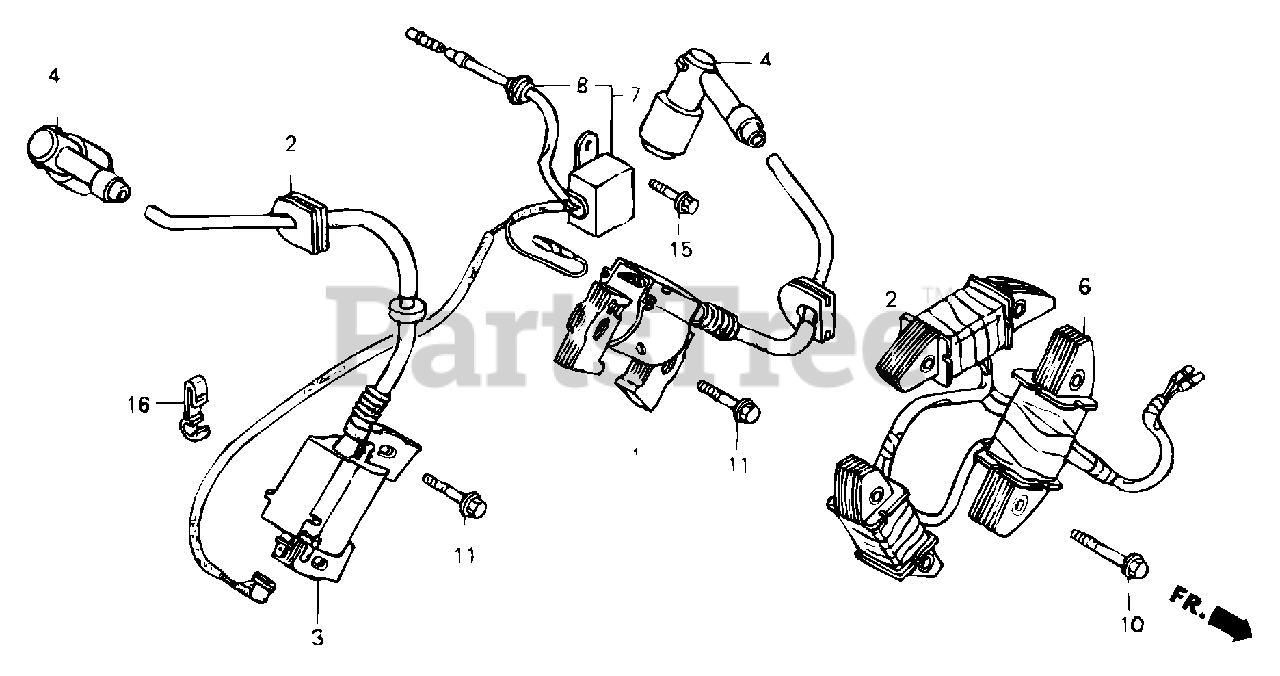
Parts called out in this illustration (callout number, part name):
1	Coil Assembly., R. Ignition
2	Grommet, Ignition Wire
3	Coil Assembly., L. Ignition
4	Cap Assembly., Noise Suppressor
6	Coil Assembly., Charge (12V/20A)
7	Diode Assembly., Engine Stop
8	Grommet, Tool
10	Bolt, Flange (6x32)
11	Bolt, Flange (6x32)
15	Bolt, Flange (6x8)
16	Clamp, Wire
